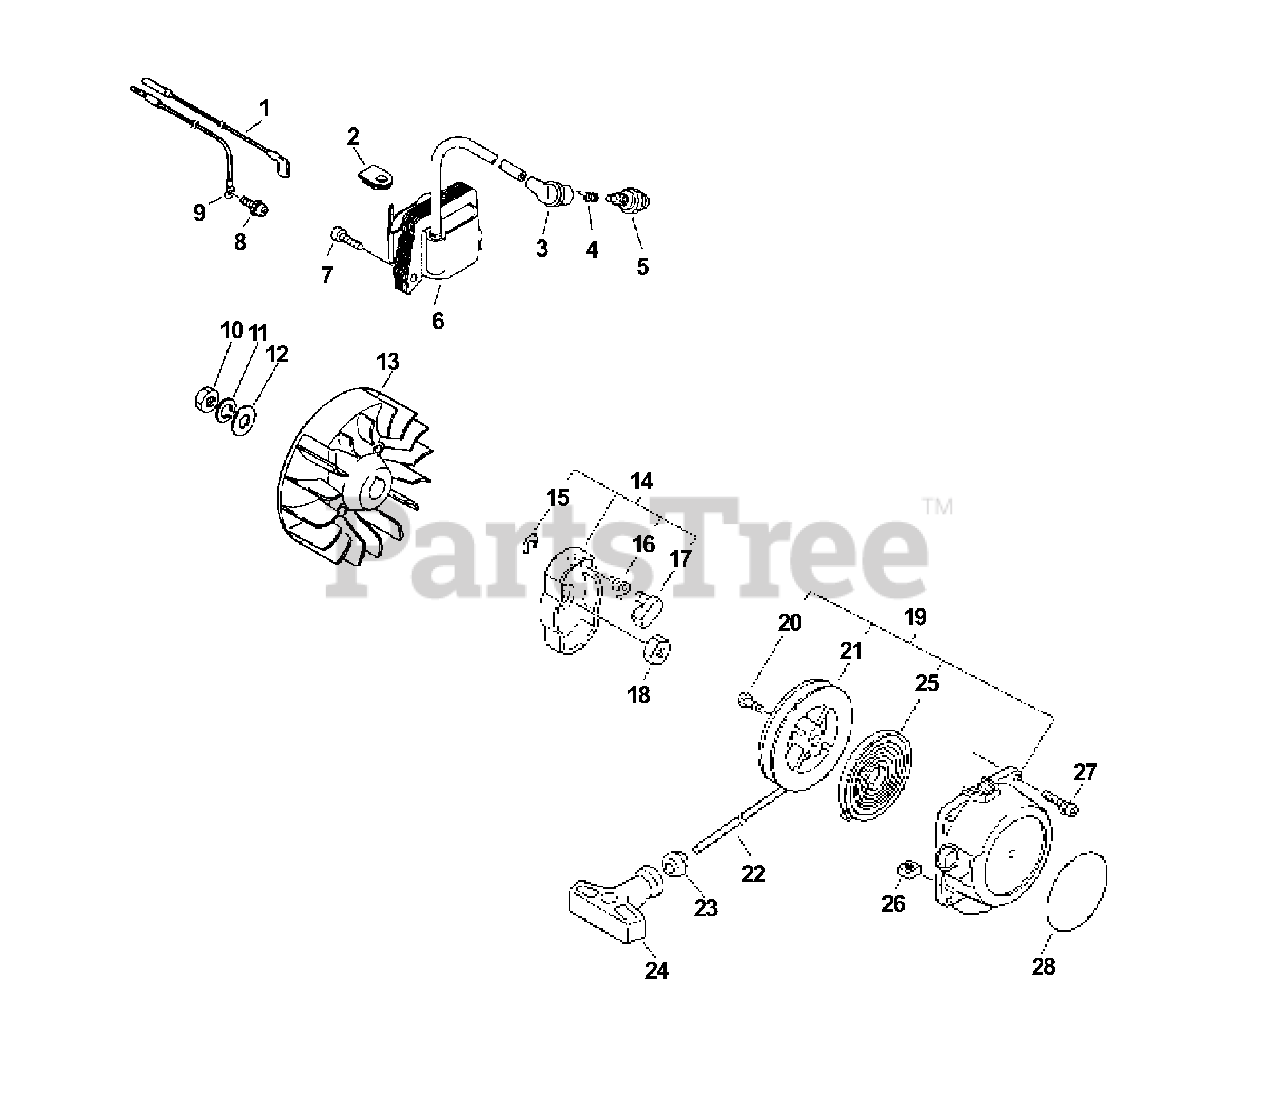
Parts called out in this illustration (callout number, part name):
1	LEAD - IGNITION 145 MM
3	CAP, SPARK PLUG
4	TERMINAL, SPARK PLUG
5	SPARK PLUG - BPM-7Y
5	SPARK PLUG - BPMR7A
6	COIL, IGNITION
7	BOLT 5×20
8	SCREW 5×10
9	LEAD - GROUND
10	NUT 8×1.25
11	WASHER, SPRING 8
12	WASHER 8.5×16×1.2
13	FLYWHEEL
14	PAWL ASSY, STARTER
15	E-RING 4
16	SPRING, RETURN
17	PAWL, STARTER
18	NUT 8×1.25
19	STARTER ASSY, RECOIL
20	SCREW
21	REEL, ROPE
22	ROPE, STARTER
23	GUIDE, ROPE
24	GRIP, STARTER
25	SPRING, RECOIL
26	NUT M5
27	BOLT 4×14
28	LABEL, ECHO
